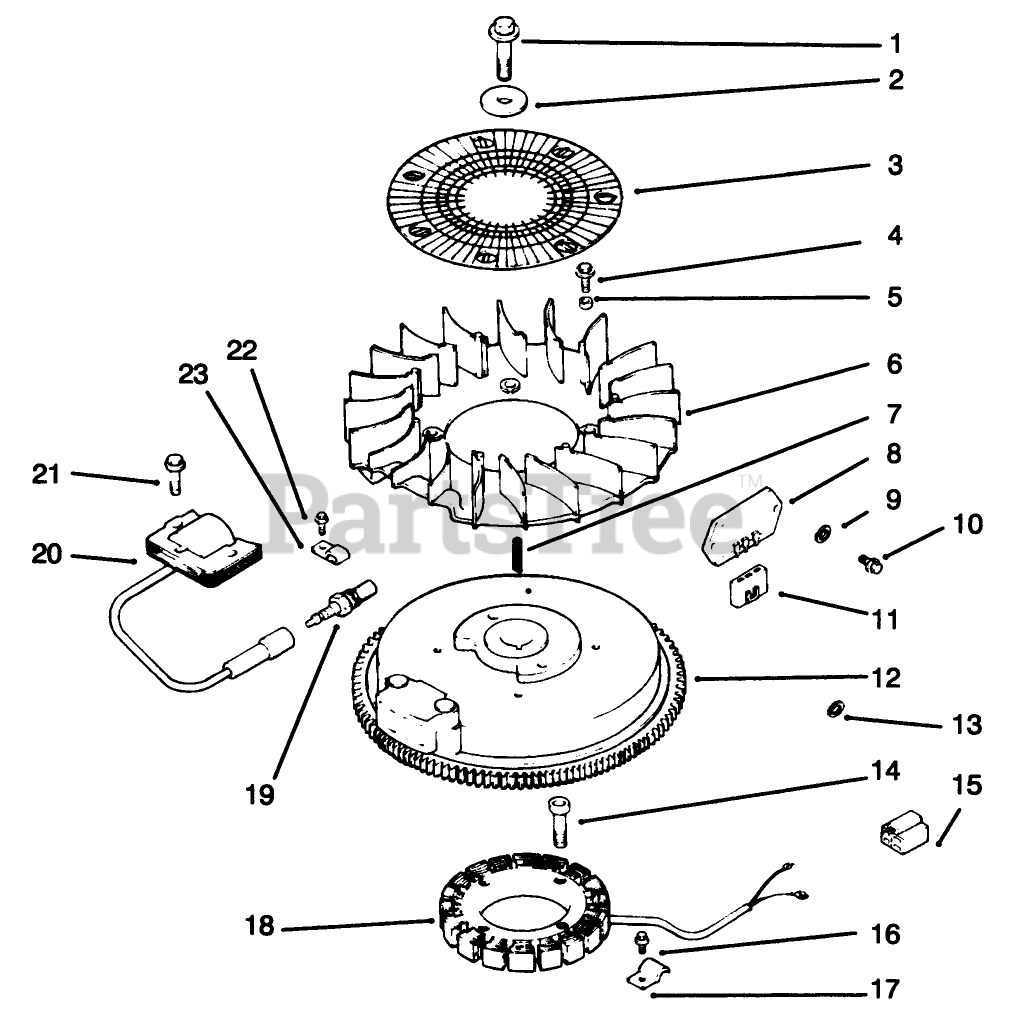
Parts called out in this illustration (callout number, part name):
1	Screw
3	Screen-Grass (Only On: 72042, 72063, 72062, 72043)
5	Spacer-Fan
6	Fan (Only On: 72042, 72063, 72062, 72043)
8	Rectifier-Regulator (Only On: 72042,72043,72062,72063)
9	Washer-Lock (Only On: 72042, 72063, 72062, 72043)
11	Connector
12	Flywheel ASM (Only On: 72042, 72063, 72062, 72043)
13	Washer-Flat (Only On: 72042, 72063, 72062, 72043)
15	Connector
17	Clip-Stator Harness (Only On: 72042, 72063, 72062, 72043)
18	Stator-15 amp
19	Spark Plug
20	Module-Ignition (Only On: 72042,72043,72062,72063)
